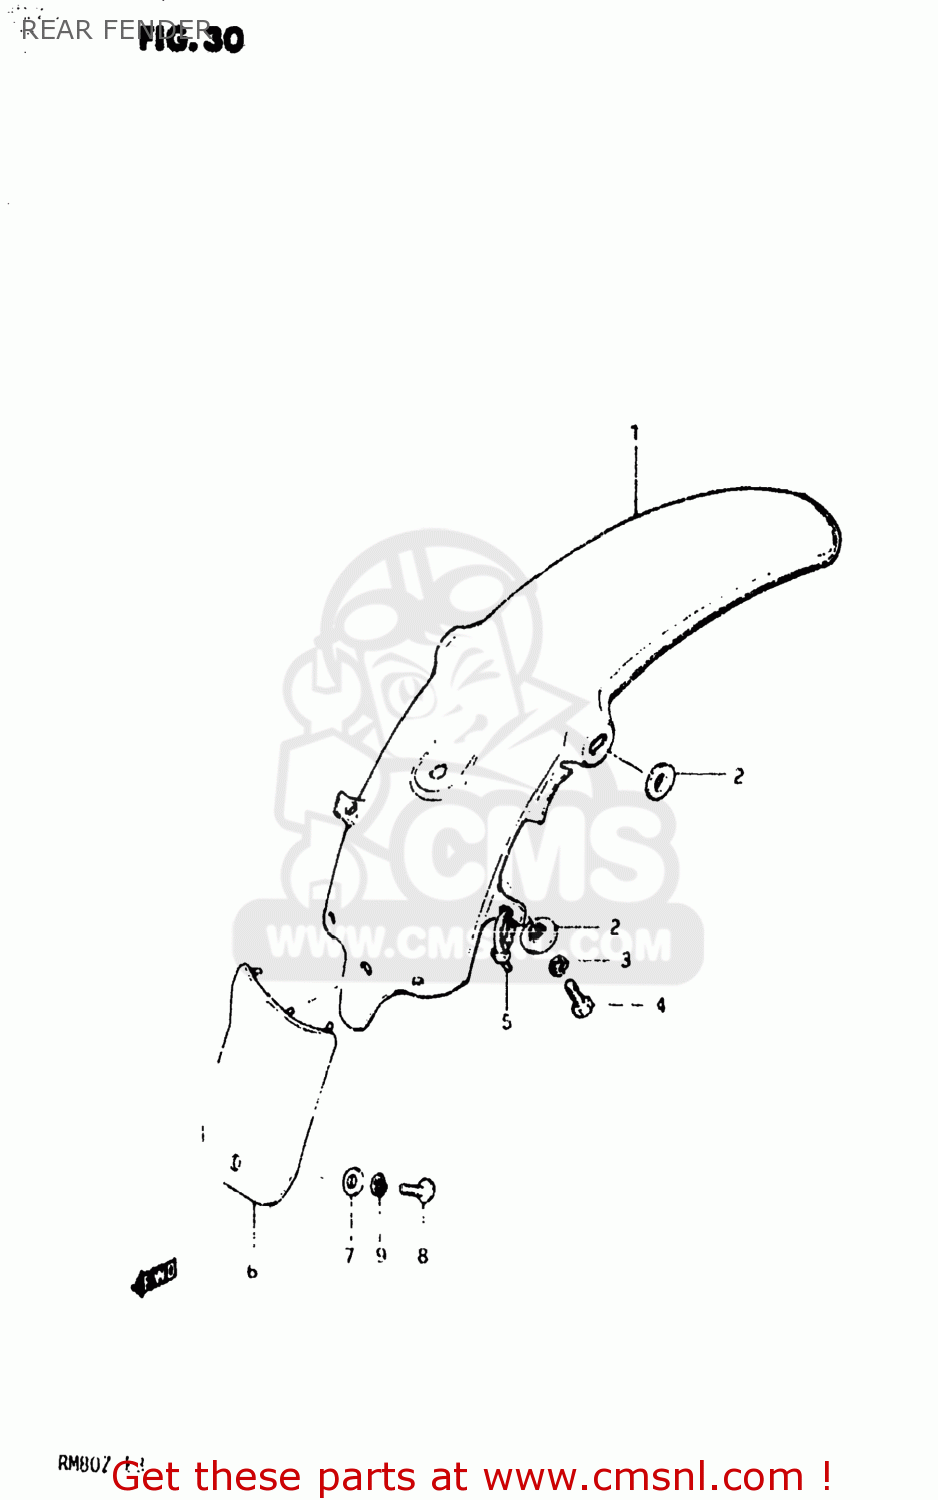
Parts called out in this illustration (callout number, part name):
1	FENDER,REAR
2	WASHER
3	LOCK WASHER
4	BOLT, UPPER
5	CLAMP
6	MUD GUARD,REAR FENDER
7	WASHER
8	BOLT
9	LOCK WASHER
